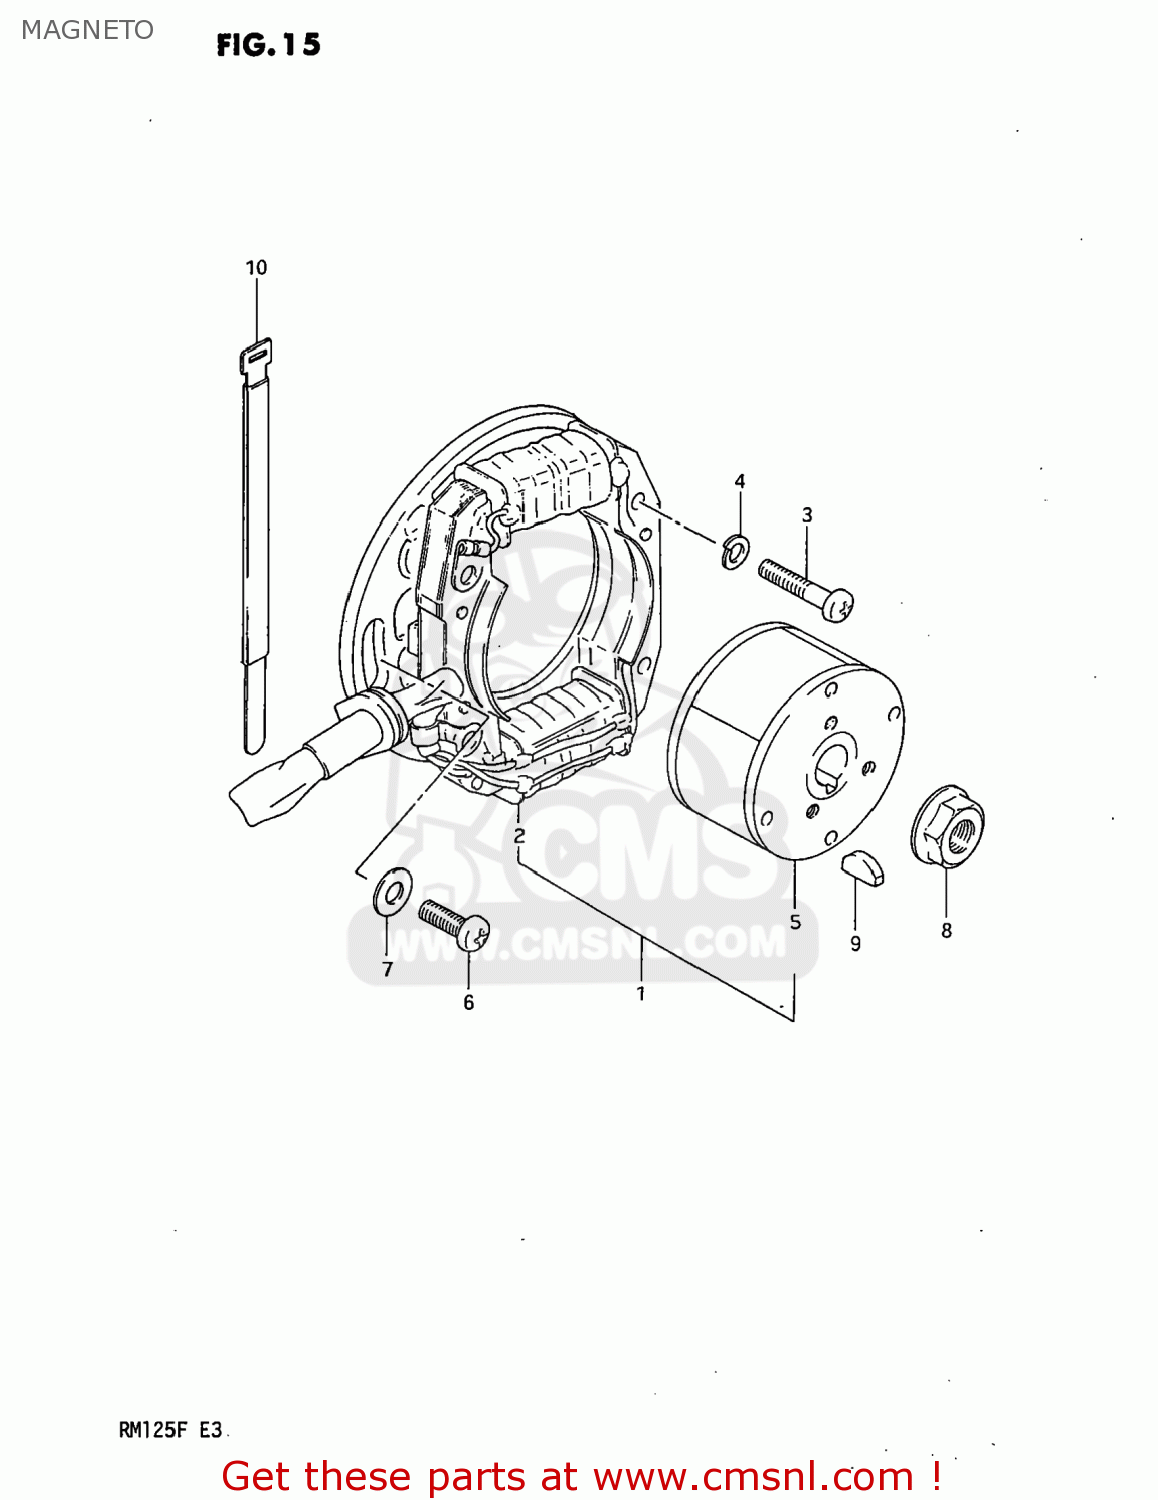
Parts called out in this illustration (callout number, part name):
1	MAGNETO ASSEMBLY
2	STATOR ASSEMBLY
3	SCREW 5X20
4	LOCK WASHER
5	ROTOR ASSEMBLY
6	SCREW
7	WASHER
8	NUT
9	KEY 4MM
10	CLAMP
